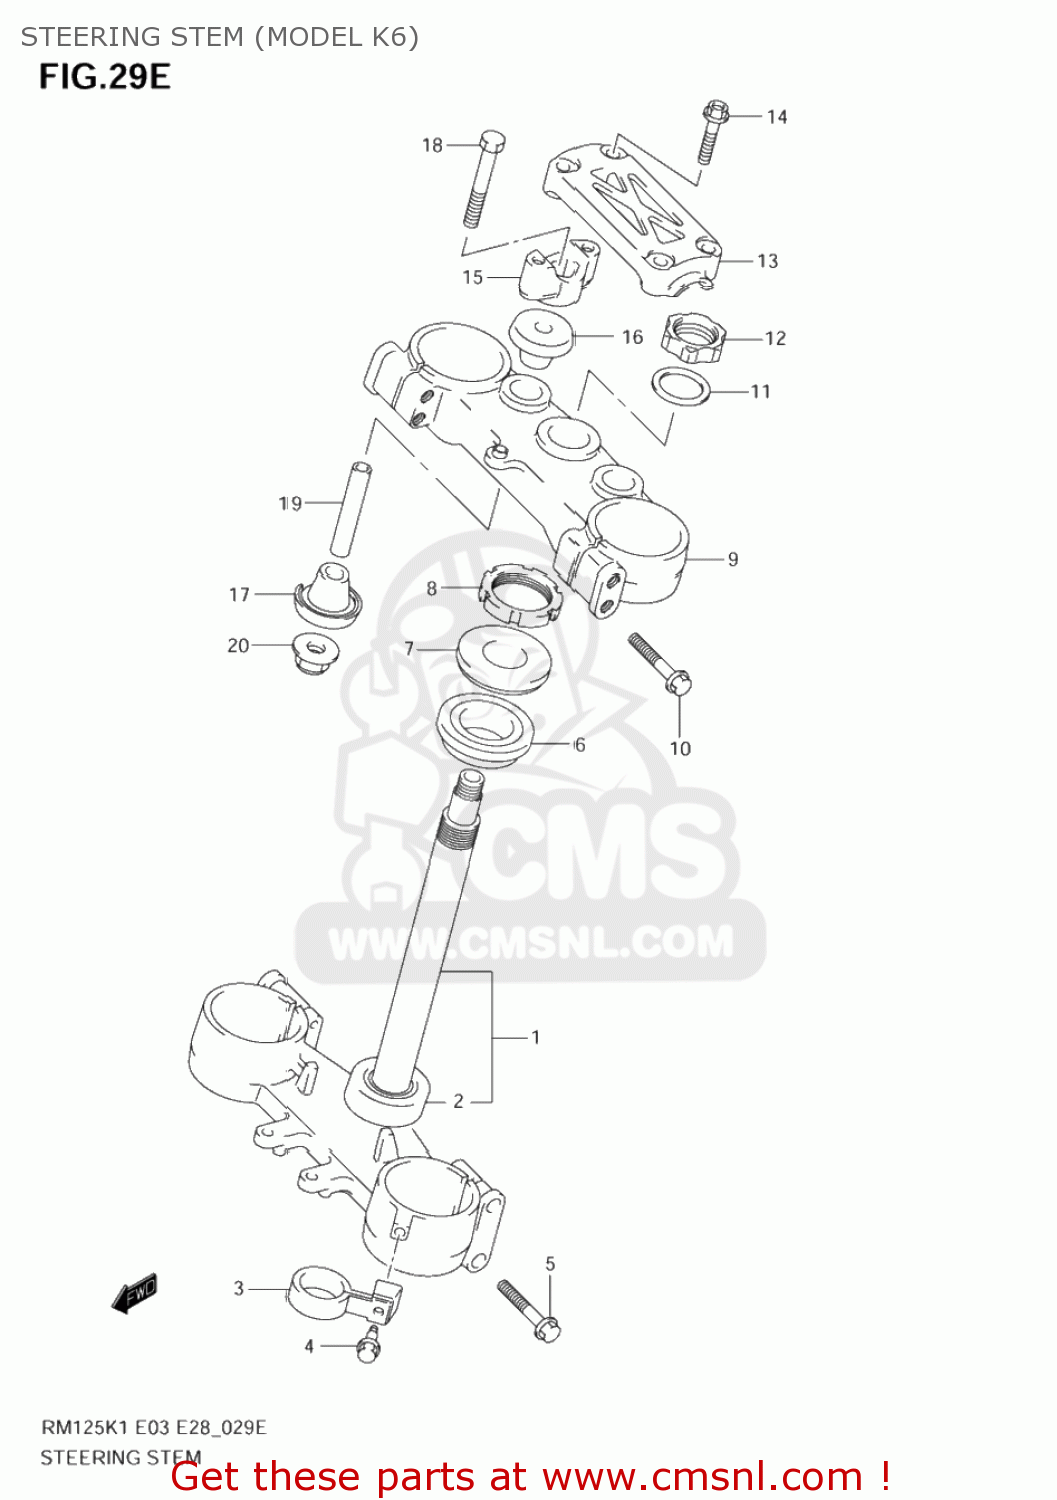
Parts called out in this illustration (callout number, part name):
1	STEM,STEERING
2	BEARING(30X52X16)
3	GUIDE,FR BRAKE HOSE
4	BOLT(6X20.5)
5	BOLT
6	BEARING(30X52X16)
7	SEAL,STEERING UPR DUST
8	NUT,STEERING
9	HEAD,STEERING STEM
10	BOLT
11	WASHER,STEM HEAD
12	NUT,STEM HEAD
13	HOLDER,HANDLE
14	BOLT
15	HOLDER,HANDLE LWR
16	CUSHION,RUBBER
17	CUSHION,RUBBER UNDER
18	BOLT
19	SPACER
20	NUT
